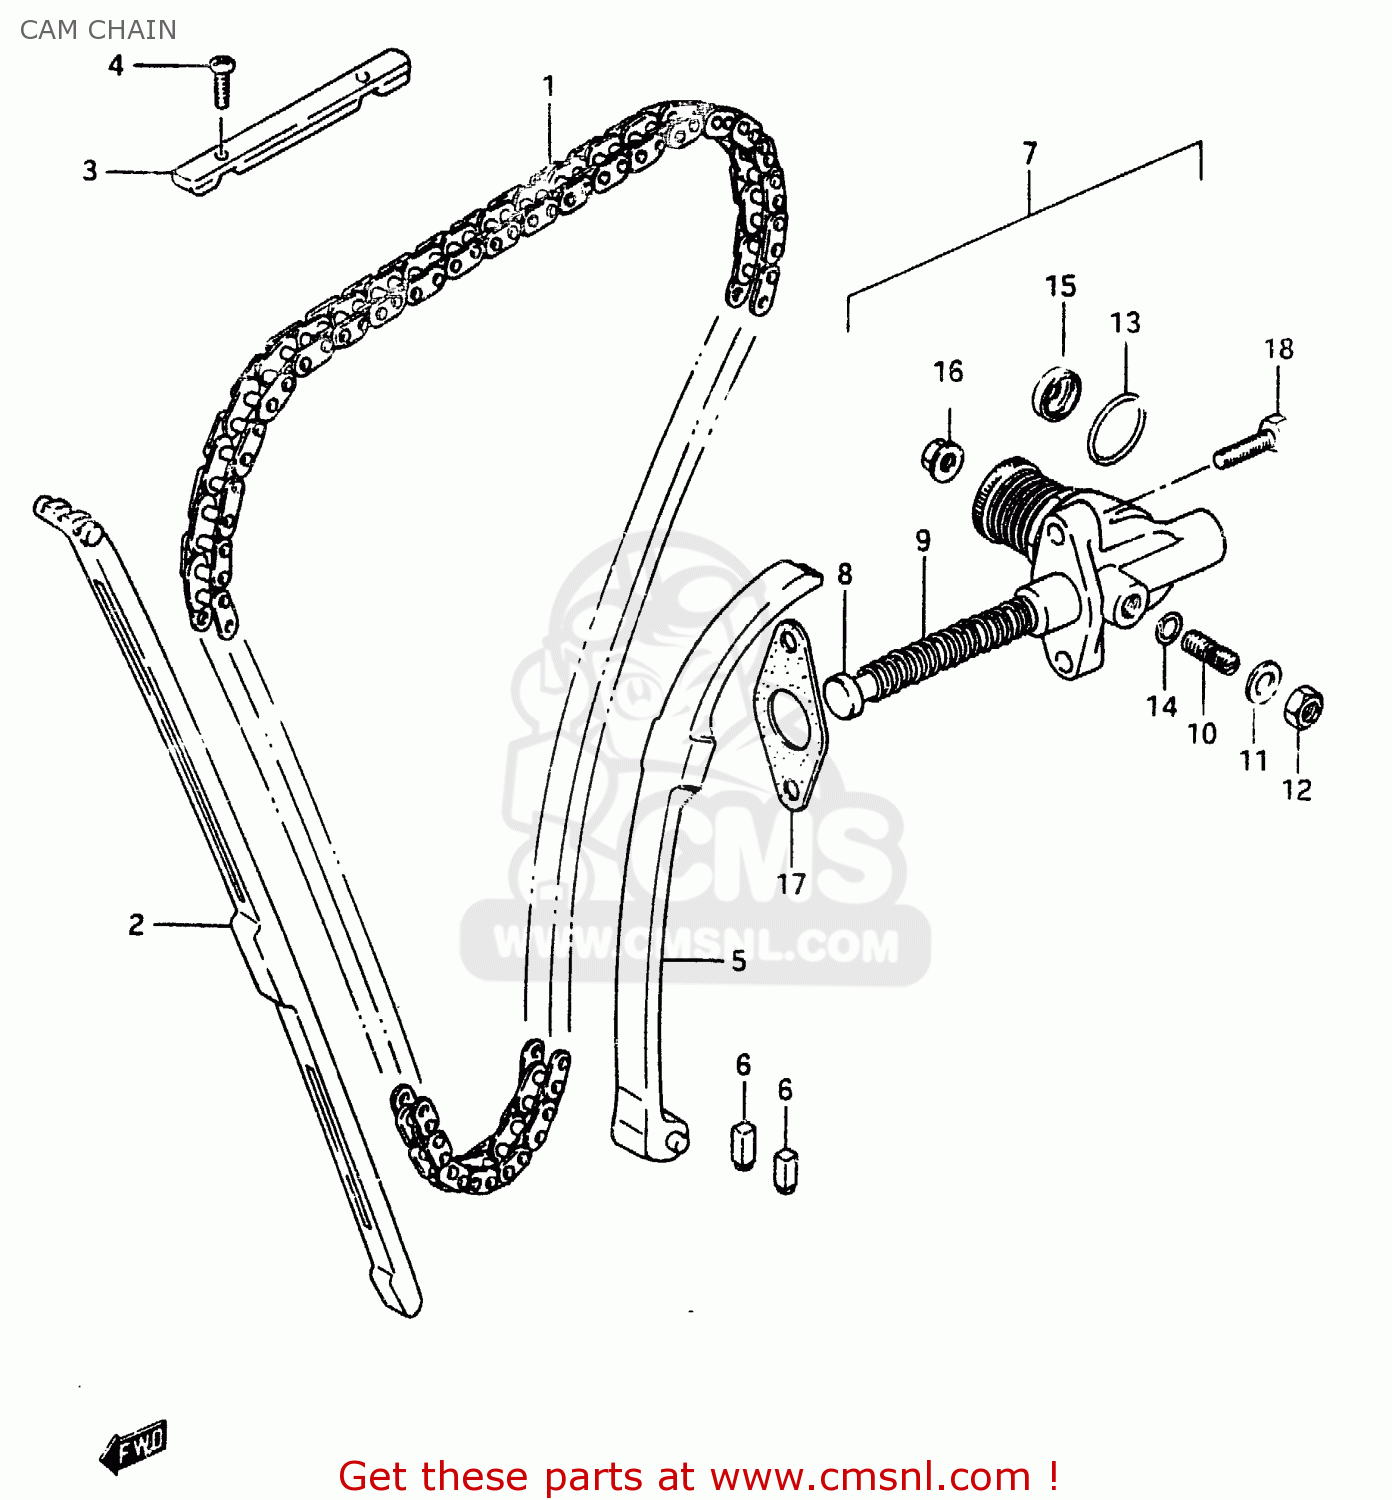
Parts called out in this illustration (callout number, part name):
1	CHAIN,CAMSHAFT DRIVE(120L)
2	GUIDE,CAM CHAIN NO.1
3	GUIDE,CAM CHAIN NO.3
4	SCREW
5	TENSIONER
6	CUSHION,CAM CHAIN TENSIONER
7	ADJUSTER ASSY,TENSIONER
8	ROD,PUSH
9	SPRING
10	SCREW,TENSIONER ADJUST
11	WASHER
12	NUT
13	O RING(D:2.4,ID:20.8)
14	O RING(D:1.9,ID:5.7)
15	SEAL,OIL(10X16X4)
16	NUT 6MM
17	GASKET,TENSIONER ADJUSTER (MCA)
18	SCREW
